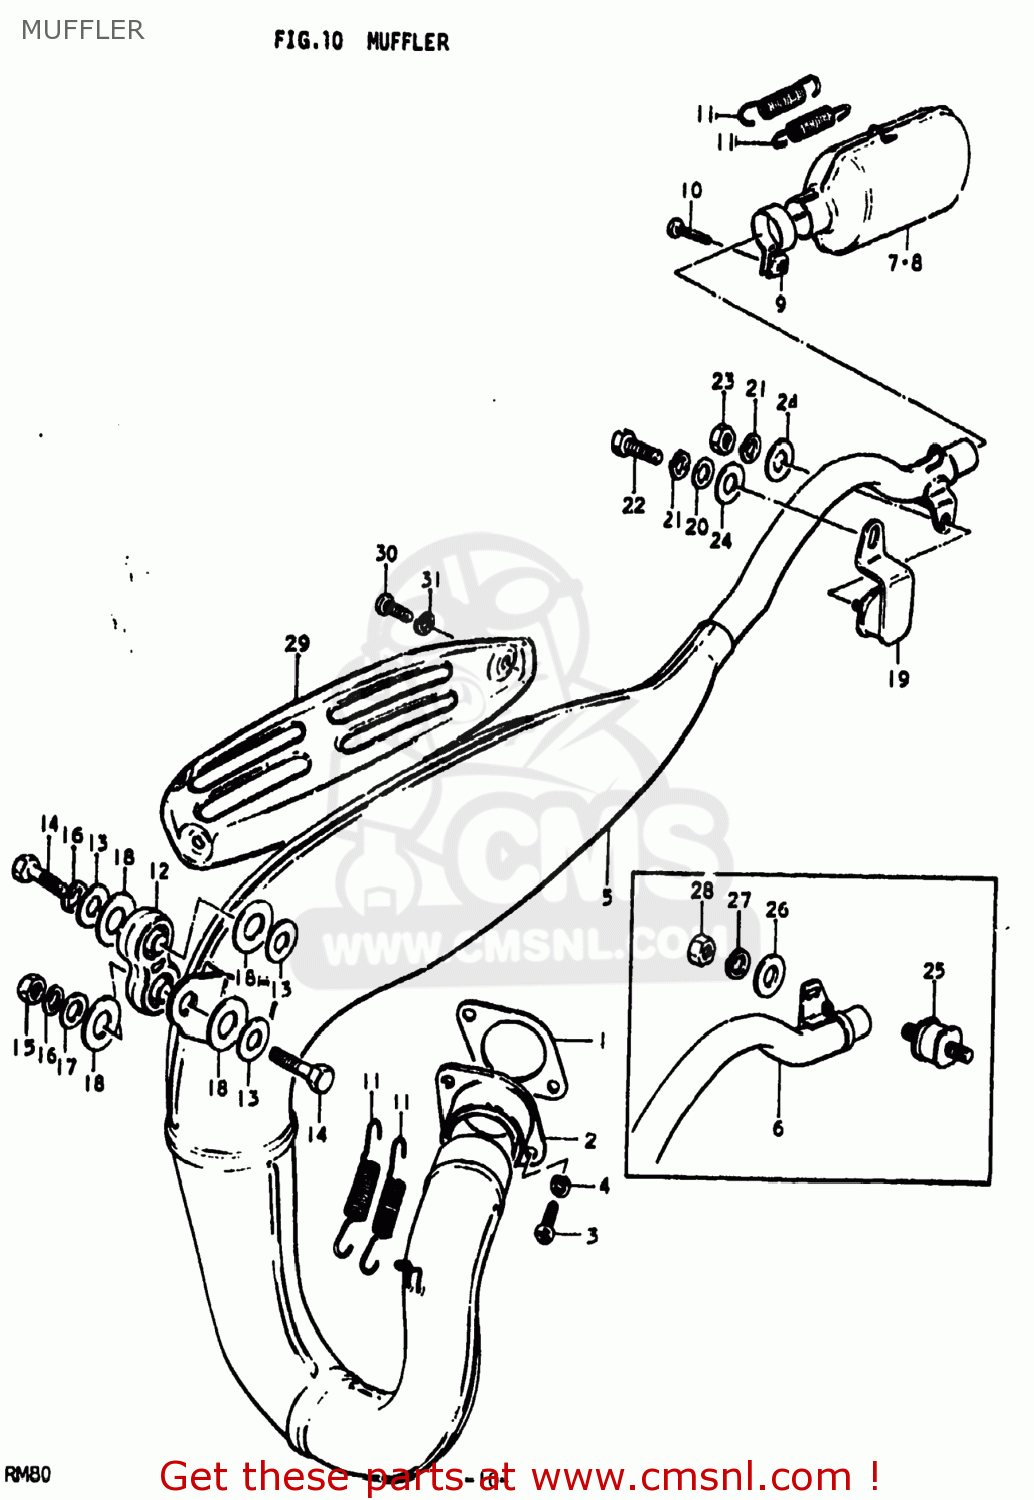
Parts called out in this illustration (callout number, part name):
1	GASKET,EXHAUST PIPE (MCA)
2	PIPE,CENTER EXHAUST
3	SCREW
4	LOCK WASHER
5	BODY,MUFFLER
6	BODY,MUFFLER
7	BODY,MUFFLER
8	BODY,MUFFLER
9	CLAMP
10	BOLT(6X20)
11	SPRING
12	DAMPER,MUFFLER
13	WASHER
14	BOLT
15	NUT
16	LOCK WASHER
17	WASHER
18	WASHER(13X28X1.6)
19	DAMPER,MUFFLER SUPPORT
20	WASHER
21	LOCK WASHER
22	BOLT
23	NUT
24	WASHER (8.2X20X1.6)
25	DAMPER,MUFFLER SUPPORT
26	WASHER
27	LOCK WASHER
28	NUT
29	COVER,MUFFLER
30	SCREW
31	LOCK WASHER
